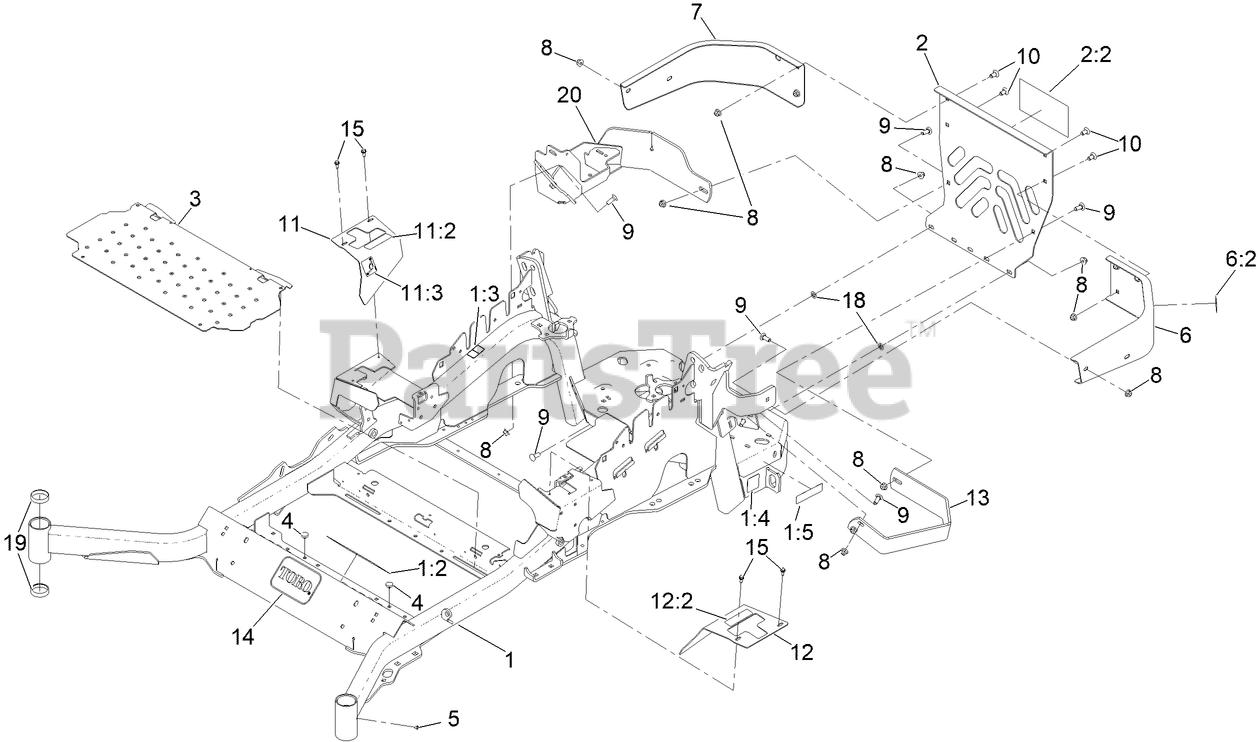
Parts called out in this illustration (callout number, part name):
1	MAINFRAME SERVICE ASM - 72
1:2	DECAL-WARNING
1:3	DECAL-DANGER
1:4	DECAL-HAZARD, PINCHED FINGER
1:5	DECAL-ARRESTOR, SPARK
2	REAR GUARD ASM
2:2	DECAL
3	FLOORPAN
4	BUMPER
6	LH BUMPER ASM
6:2	DECAL-WARNING
7	BUMPER-RH
8	NUT-HF, NI
9	SCREW-CARR
10	SCREW-CARR
11	RH MOTION CONTROL COVER ASM
11:2	DECAL-CONTROL, MOTION
11:3	DECAL-PARK BRAKE, CE
12	LH MOTION CONTROL COVER ASM
12:2	DECAL-CONTROL, MOTION
13	GUARD-MUFFLER
14	DECAL
15	SCREW-HWH
18	NUT-PUSH
19	CUP-BEARING
20	BATTERY GUARD ASM
